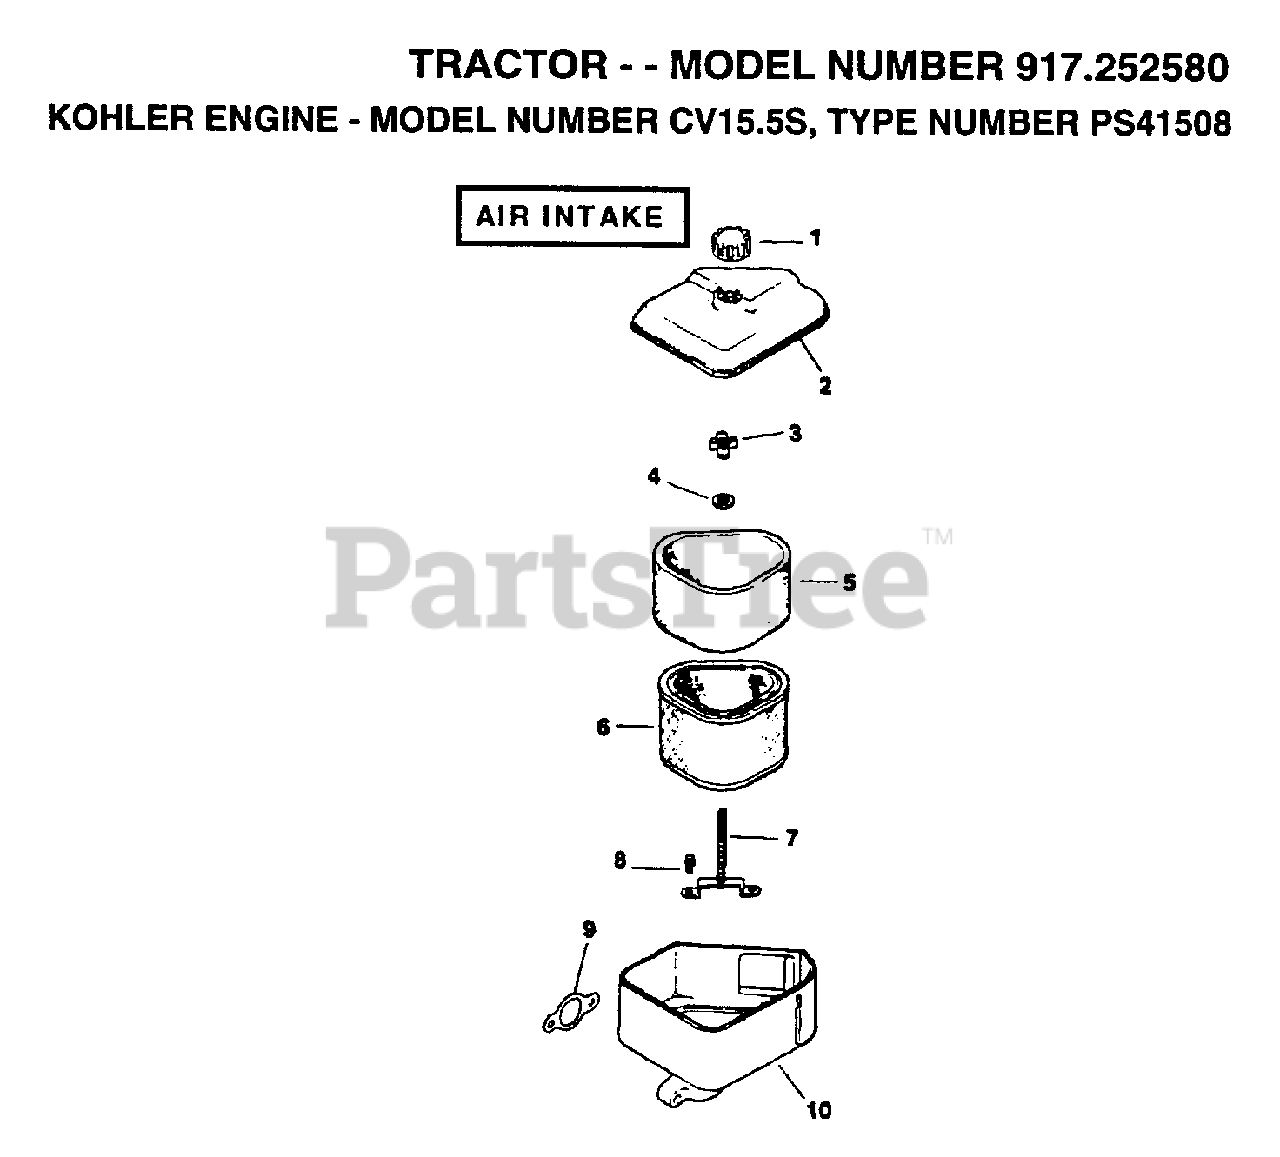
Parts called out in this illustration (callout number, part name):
1	KNOB, AIR CLEANER COVER
2	COVER, AIR CLEANER
4	WASHER, PLAIN 1/4
5	PRECLEANER ELEMENT
6	ELEMENT, AIR CLEANER
7	STUD, MOUNTING PLATE
8	SCREW, MOUNTING PLATE STUD
9	GASKET, AIR CLEANER
10	BASE, AIR CLEANER
